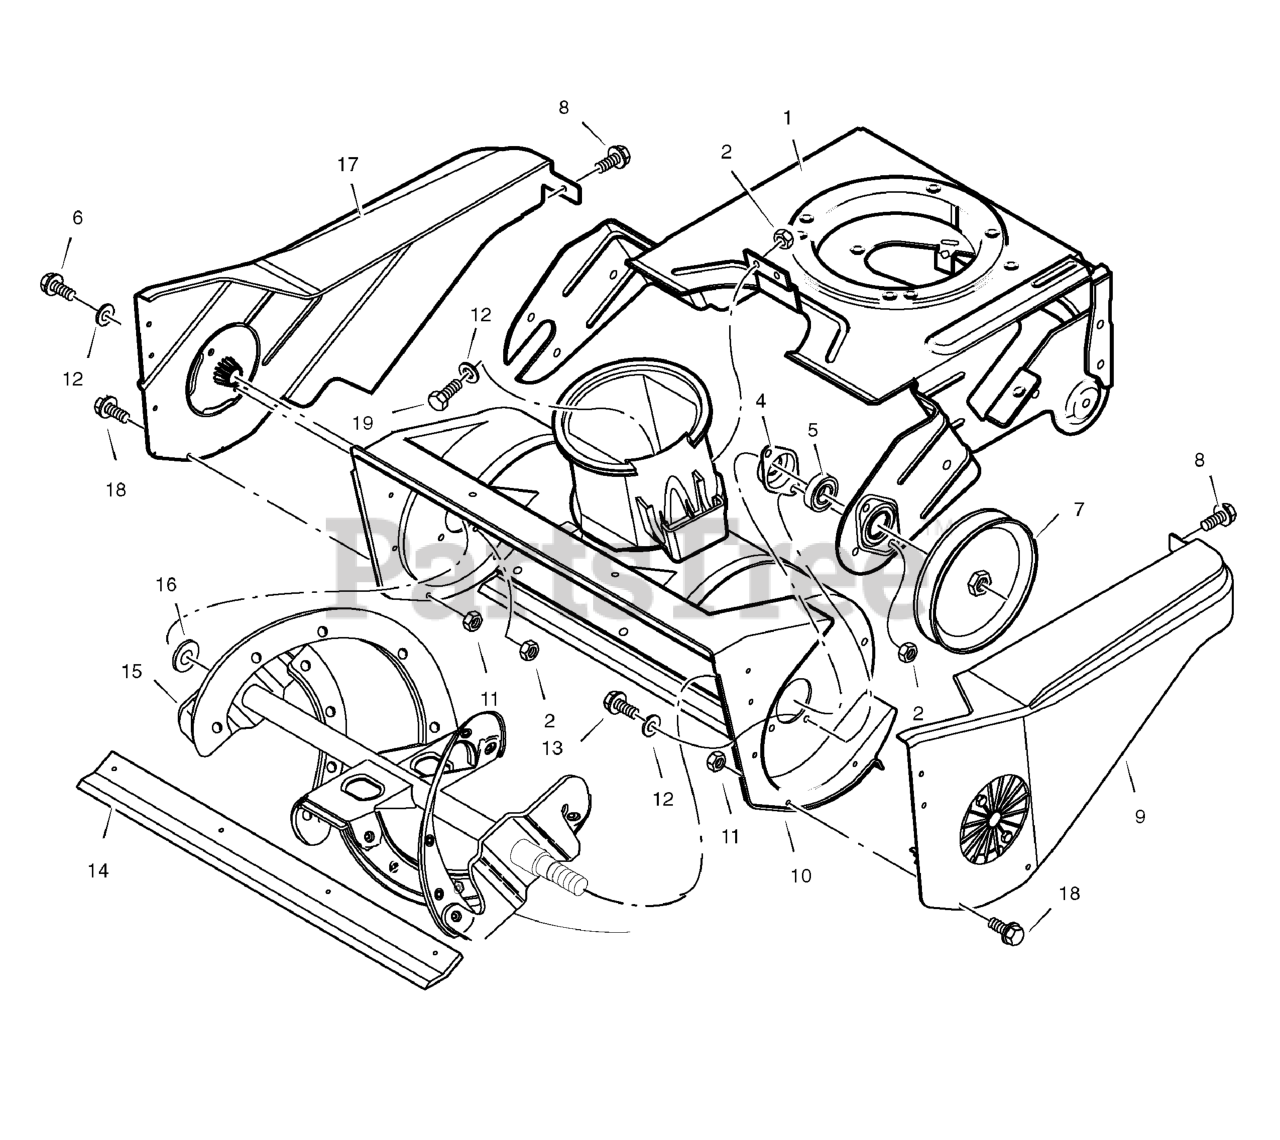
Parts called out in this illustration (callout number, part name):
1	Frame, Motor Box
4	Retainer, Bearing
5	Bearing
7	Pulley, Auger
9	Cover, Left Belt
10	Assembly, Auger Housing
11	Nut
12	Washer
14	Blade, Scraper
15	Auger Assembly
17	Cover, Right
